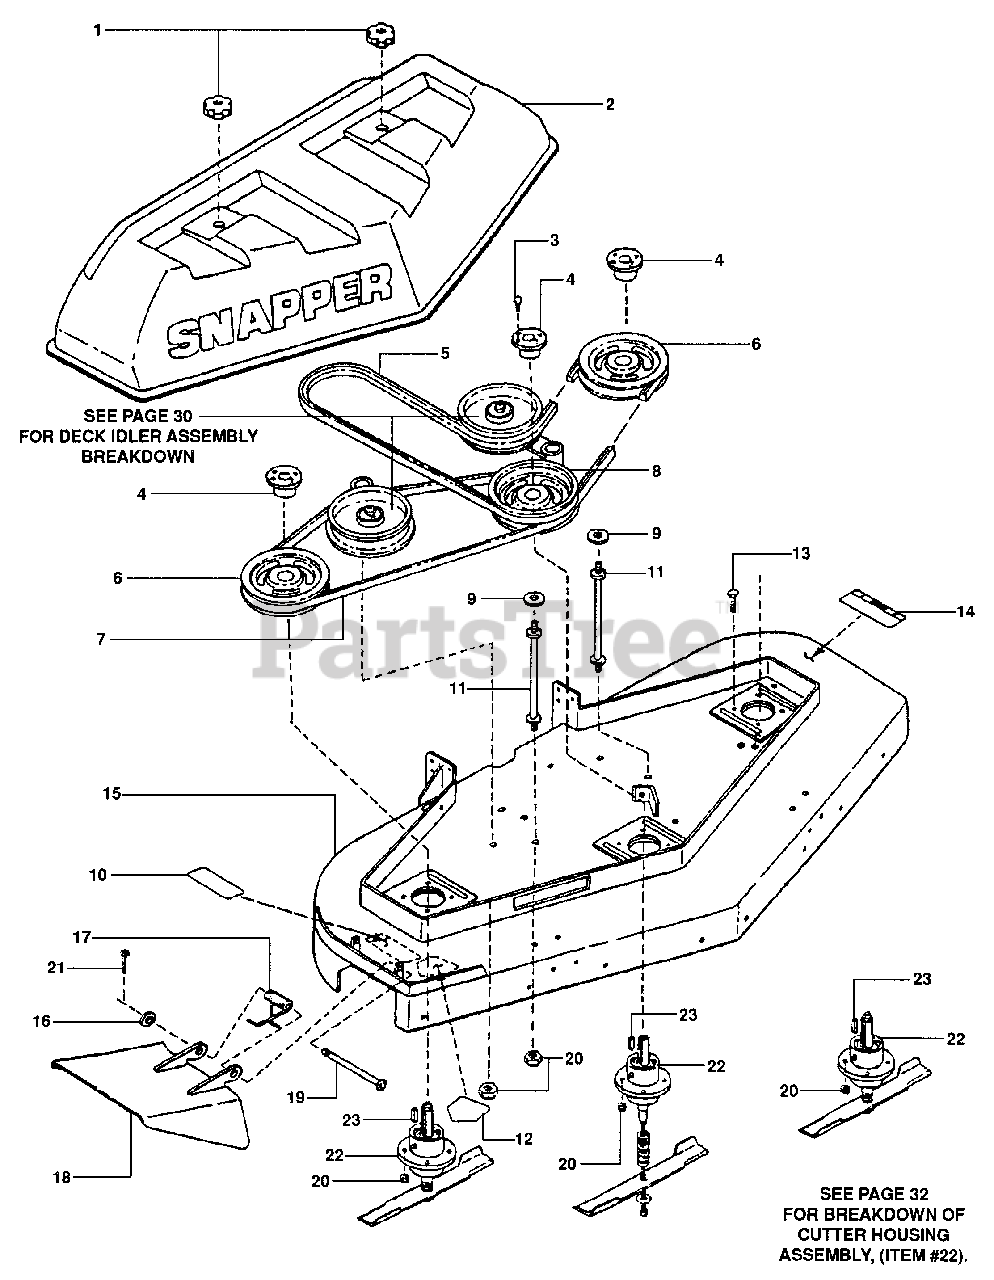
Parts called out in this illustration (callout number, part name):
1	KNOB, Hood
2	HOOD
3	BOLT, 1/4-20 X 7/8" Hex Head Cap
4	BUSHING, Taperlock
5	BELT, Engine To Deck
6	PULLEY, Cutter Blade Drive
7	BELT, Blade
8	PULLEY, Cutter Blade Drive (Double Groove)
9	WASHER, 13/32" I.D. X 1-1/2" O.D.
10	DECAL, Caution
11	STUD, Hood Mount
12	DECAL, Danger
13	SCREW, 3/8-16 X 1 1/4 Hex Head Cap
14	DECAL, Caution
15	WELDMENT, 48" Deck
16	WASHER, 5/16 Flat
17	SPRING, Chute
18	DEFLECTOR, Chute, 48" Deck
19	ROD, Chute Pivot
20	NUT, 3/8-16 Hex (Nyloc)
21	PIN, 3/32 X 1" Cotter
22	ASSEMBLY, Cutter Housing
23	KEY, Spindle
